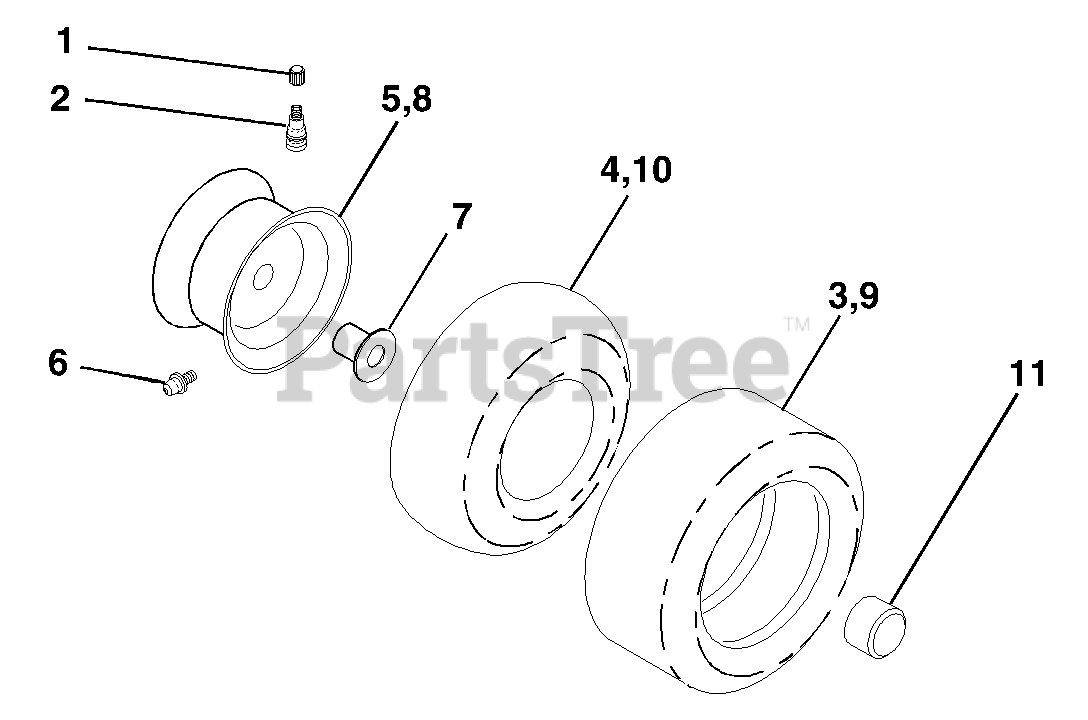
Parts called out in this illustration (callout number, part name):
1	Cap Valve Tire
2	Stem Valve
3	Tire F T 15 X 6 0 - 6 Service
4	Tube Front
5	Rim Asm 6" front Service
6	Fitting Grease
7	Bearing Flange
8	Rim Asm 8" rear Service
9	Tire R T 20x10-8 Service
10	Tube Rear
11	Cap Axle Blk 1 50 X 1 00
